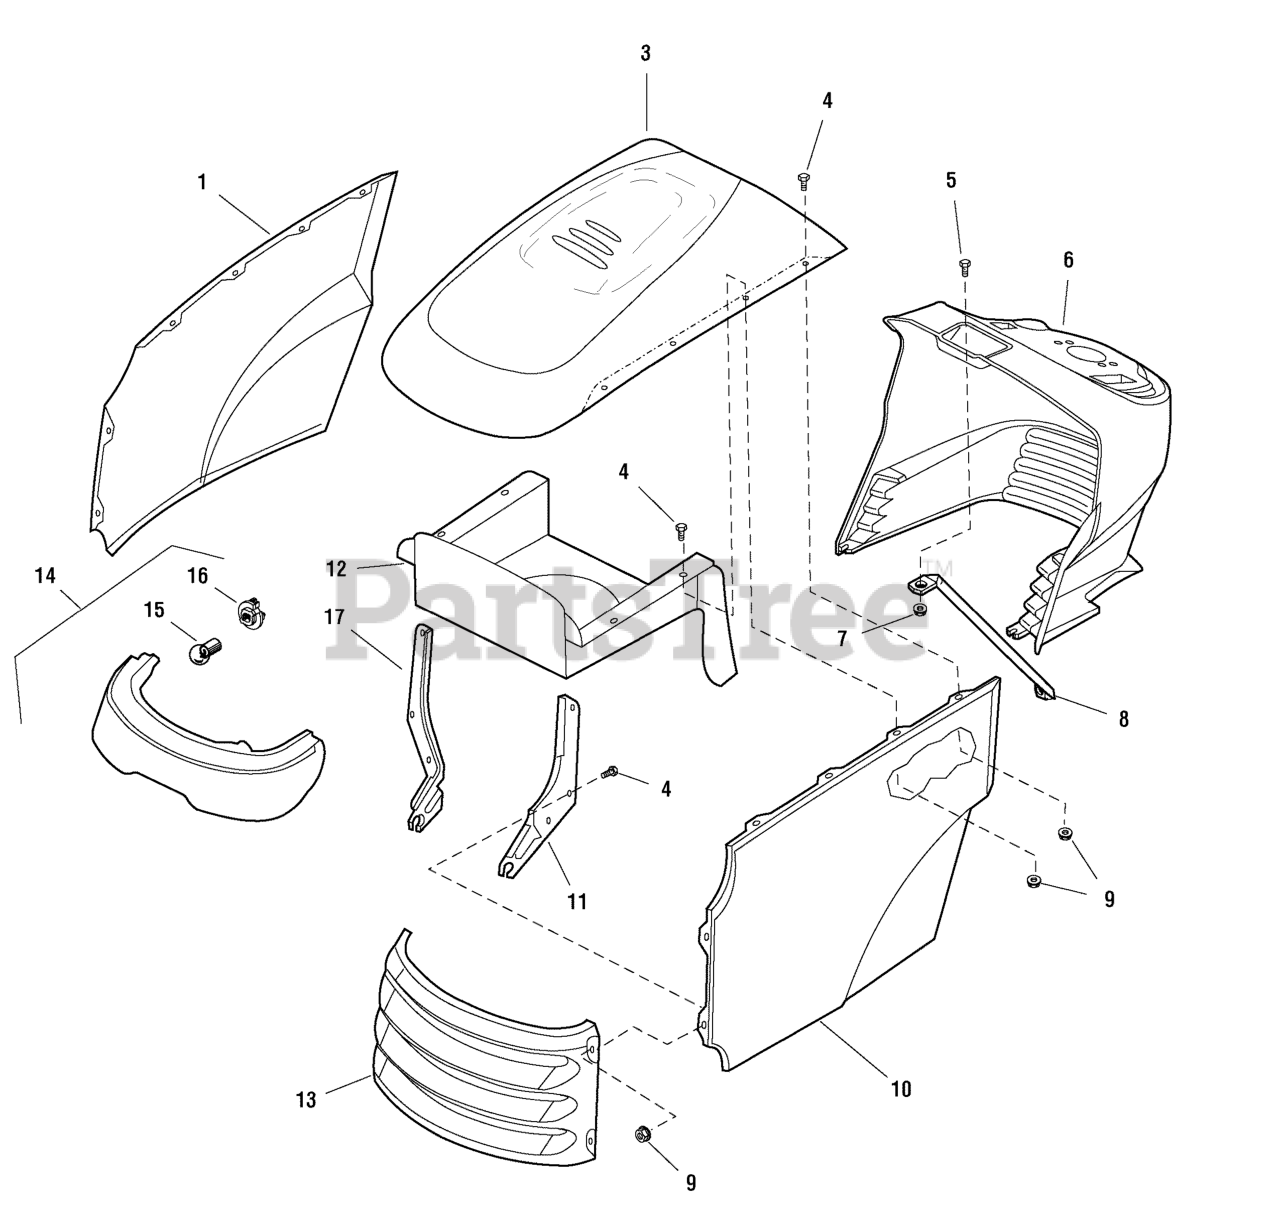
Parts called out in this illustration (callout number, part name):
1	PANEL, RH Side
3	HOOD, with Louvers
4	CAPSCREW, Hex Head Flange Lock,1/4-20 x 5/8
5	SCREW, Pan Head Phillips, #10-24 x 1
6	DASHBOARD, RMO, Black
7	NUT, Hex Nylock,#10-24
8	ROD, Dash Support
9	NUT, Hex Flange Lock, 1/4-20
10	PANEL, LH Side
11	HINGE, LH
12	DUCT, Air Inlet
14	HEADLIGHT ASSEMBLY
15	BULB, Headlight
16	SOCKET, Headlight
17	HINGE, RH
